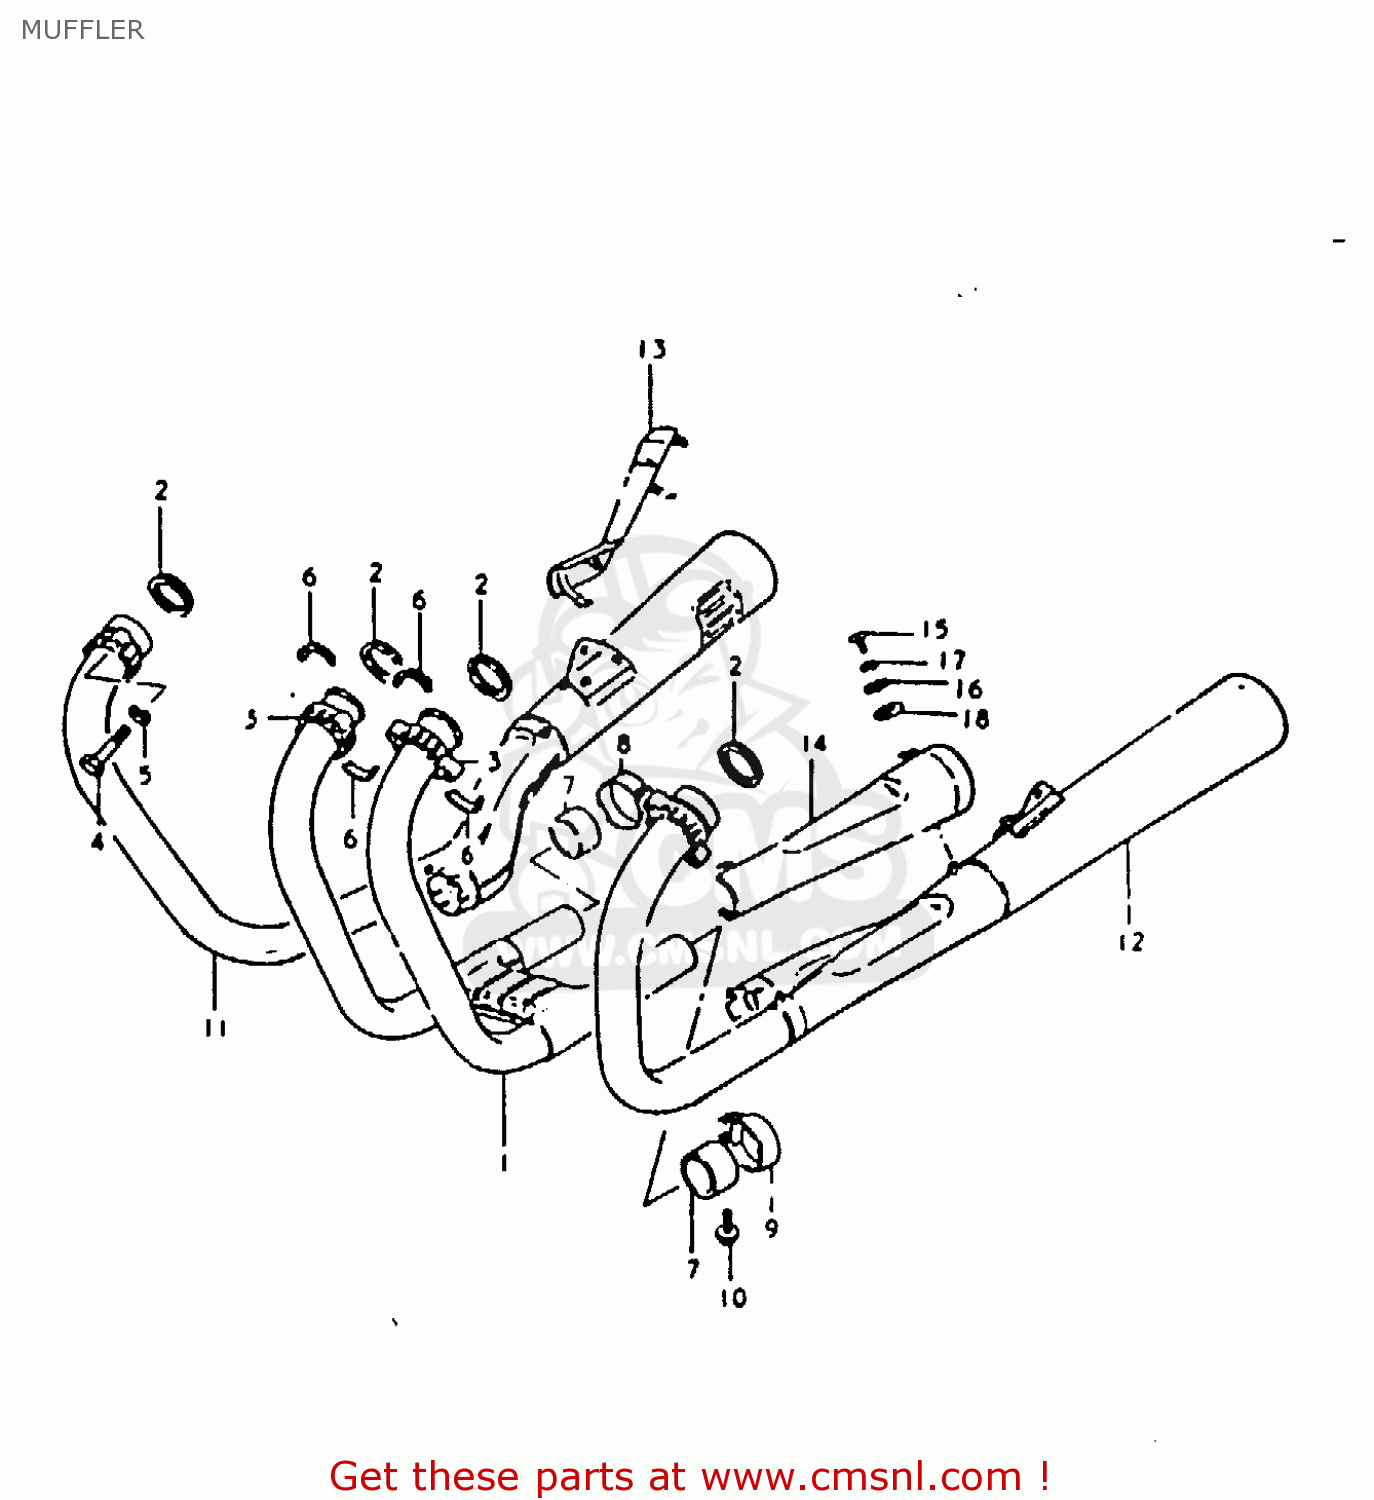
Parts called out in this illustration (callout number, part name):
1	PIPE,EXHAUST,CENTER
2	GASKET,EXHAUST PIPE (NAS)
3	CLAMP,EXHAUST PIPE
4	BOLT
5	LOCK WASHER
6	PLATE,EXHAUST P
7	CONNECTOR,MUFFLER
8	CLAMP,MUFFLER CONNECTOR,R
9	CLAMP,MUFFLER CONNECTOR,L
10	BOLT
11	MUFFLER, RH
12	MUFFLER, LH
13	COVER,MUFFLER
14	COVER,MUFFLER
15	SCREW
16	WASHER
17	LOCK WASHER
18	GASKET 6.2X12X1.5 (MCA)
